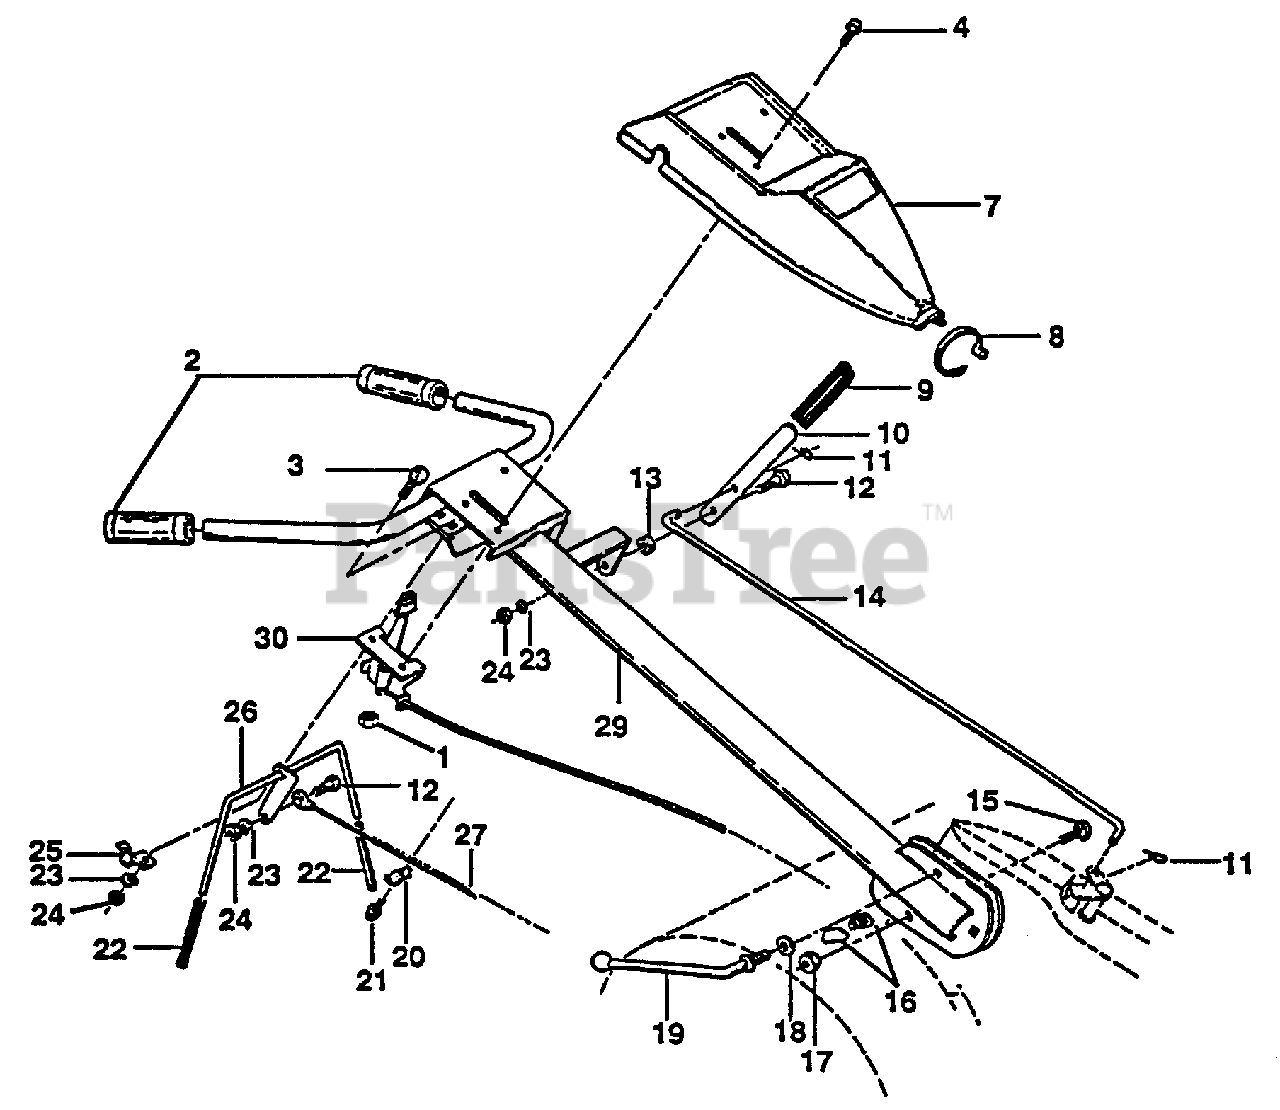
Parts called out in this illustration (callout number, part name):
1	Nut, Keps #10-24 UNC
2	Grip, Handle
3	Bolt, Carriage 1/4-20
4	Screw, Truss Hd. #10-24 UNC x 1/2
7	Panel, Control
8	Tie, Cable
9	Grip, Handle
10	Handle, Shift
11	Clip, Hairpin
12	Bolt, Shoulder
13	Grommet, Rubber
14	Rod, Shift
15	Bolt, Carriage 3/8-16 x 1 Gr. 5
16	Lock, Handle
17	Nut 3/8-16
18	Washer 13/32 x 1 x 11 Ga.
19	Lever, Lock, Handle
21	Screw, Hex Washer Hd. Slotted #10-24 X 1/2
22	Grip, Bar, Control
23	Washer, Lock 1/4
24	Nut, Hex 1/4-20
25	Clamp, Bar, Control
26	Bar Assembly, Control
27	Cable, Clutch
29	Handle
30	Control, Throttle
